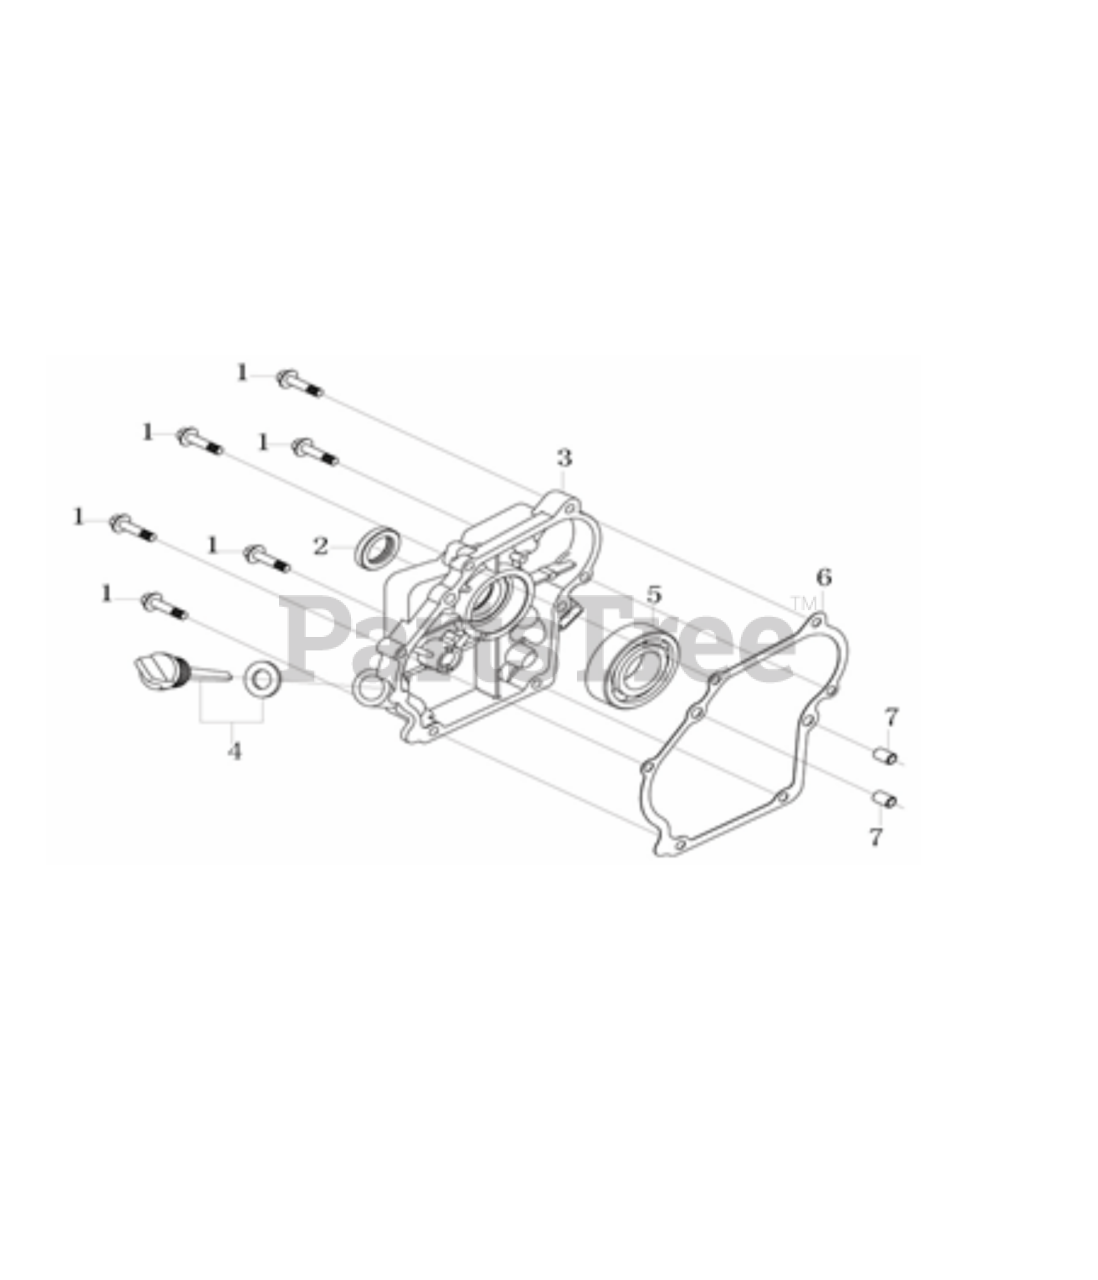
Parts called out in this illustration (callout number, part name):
1	Hexagon bolt with flange
2	Oil seal
3	Crankcase cover
4	Oil rule combination
5	Bearing
6	Crankcase cover gasket
7	Location Pin
